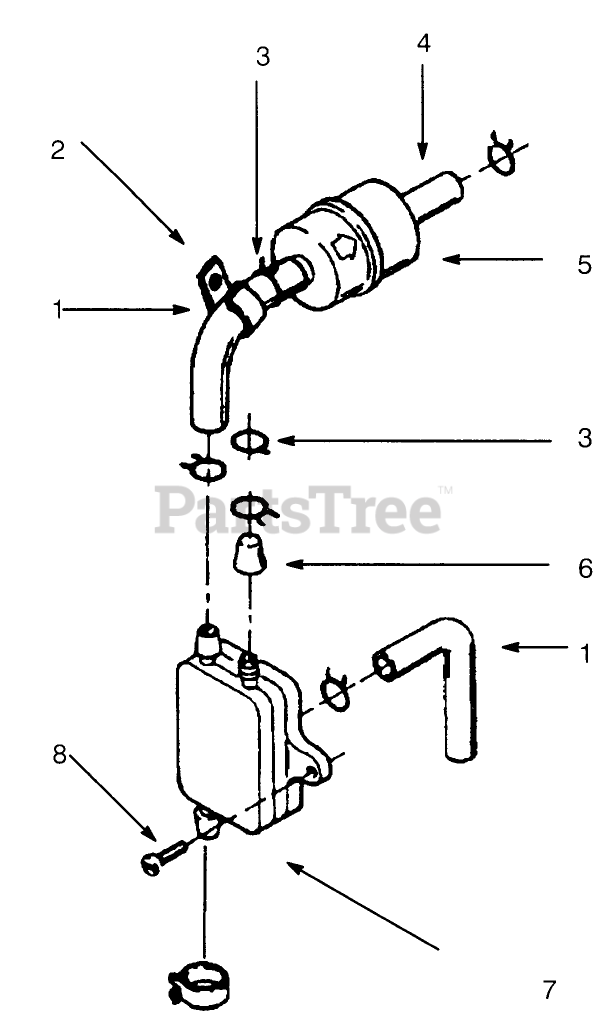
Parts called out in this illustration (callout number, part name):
3	CLAMP-HOSE
5	FUEL FILTER
6	CAP-FUEL OUTLET
8	SCREW-TAPPING PAN HD
